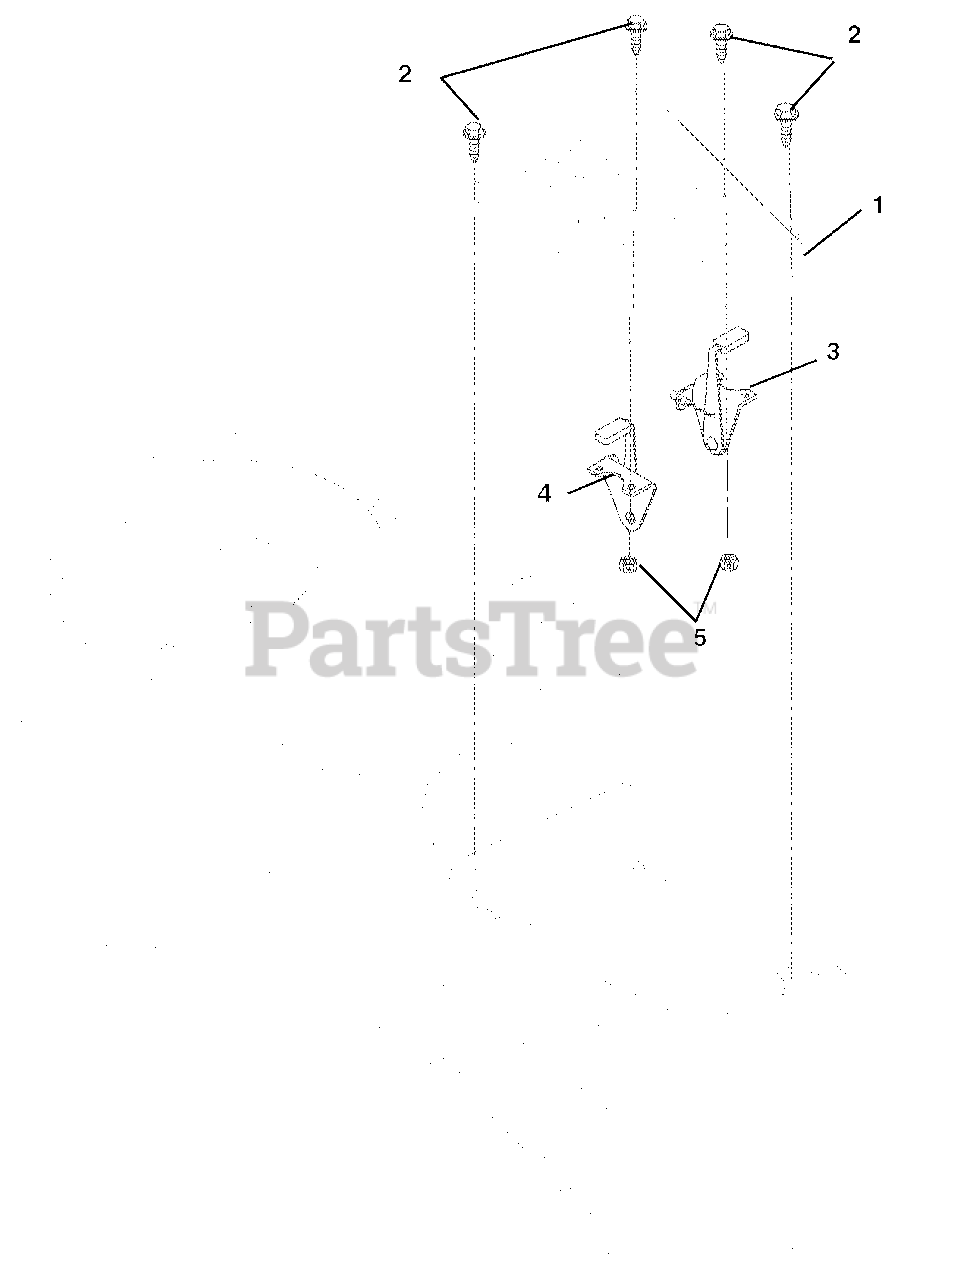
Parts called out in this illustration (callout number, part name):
1	Panel, Control
2	Screw, Machine 10-24 x .50 Hex Washer Head
3	Cable, Throttle (991026, 027, 028, 029, 030, 032)
4	Cable, Choke, Kawasaki (991026, 027, 028, 029, 030, 032)
5	Nut, Locking Nylon 10-24 With Insert
